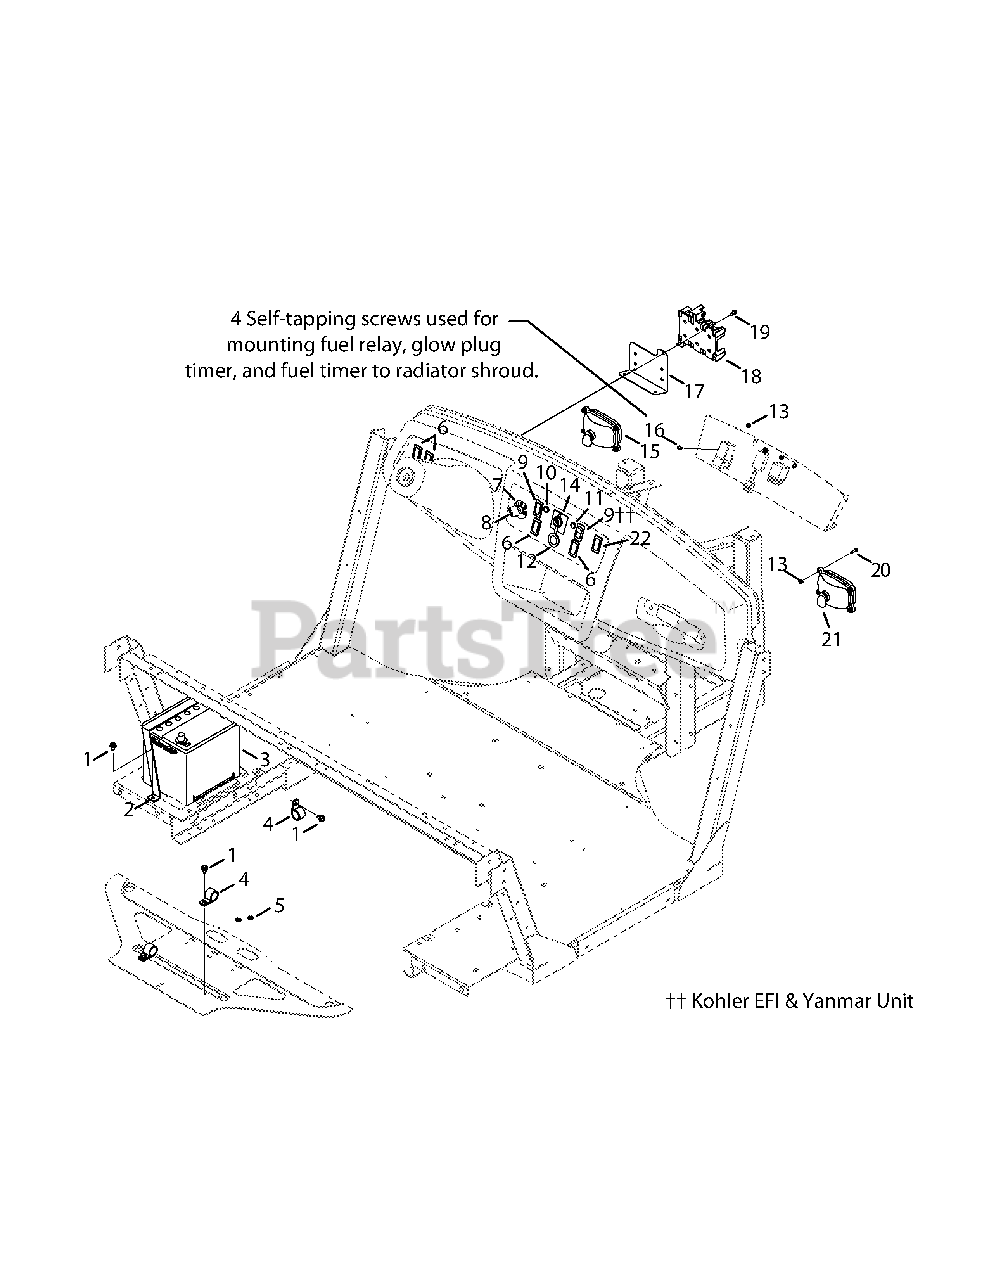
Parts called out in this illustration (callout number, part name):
1	Screw, TT, 5/16-18 x .500
2	Bracket, Mt., Battery
3	Battery, 450 CCA Wet
5	Washer, Lock, 5/16
6	Panel, Plug, Switch
7	Switch, Key, 4 Pos. Delta
8	Key, Delta, Plastic
9	Switch, 4x4, Rocker
10	Light, Ind., Yellow, LED
10	Lamp, Ind., Green, Incandescent
11	Light, Ind., Red, LED
11	Lamp, Ind., Red, Incandescent
12	Receptacle, Power, 12v
13	Nut, Hex Lock, #10-24
14	Meter, Ind., Hour Flat Face
15	Headlight Assembly (Incl. # 21)
16	Screw, #10-24 x .500
17	Bracket, Fuse Mount
18	Relay, Holder, 3-Way
19	Screw, TT, 1/4-20 x .500
20	Screw, TT, #10-24 x .750
21	Head lamp Bulb
22	Seat Belt Indicator
